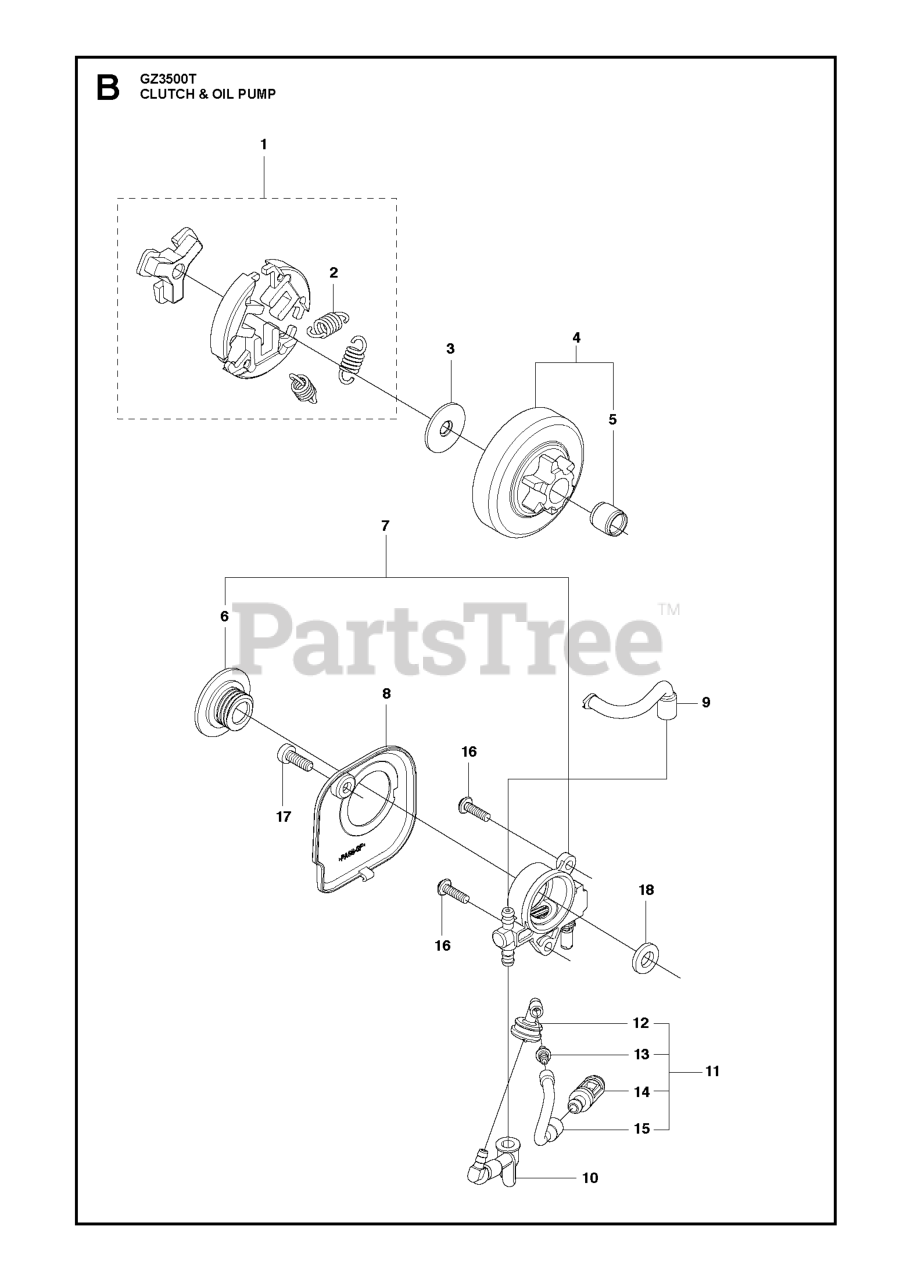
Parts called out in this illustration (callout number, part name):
1	CLUTCH-ASSY
5	ROLLER BEARING
6	OIL PUMP (WORM 199-18)
7	OIL PUMP SET(RPLS 284155112
8	COVER, PUMP
9	PIPE
10	PIPE IN COMP
11	FILTER COMPLETE
12	OIL FILTER
14	RP_FILTER
15	PIPE (GZ3500T)
16	SCREW
